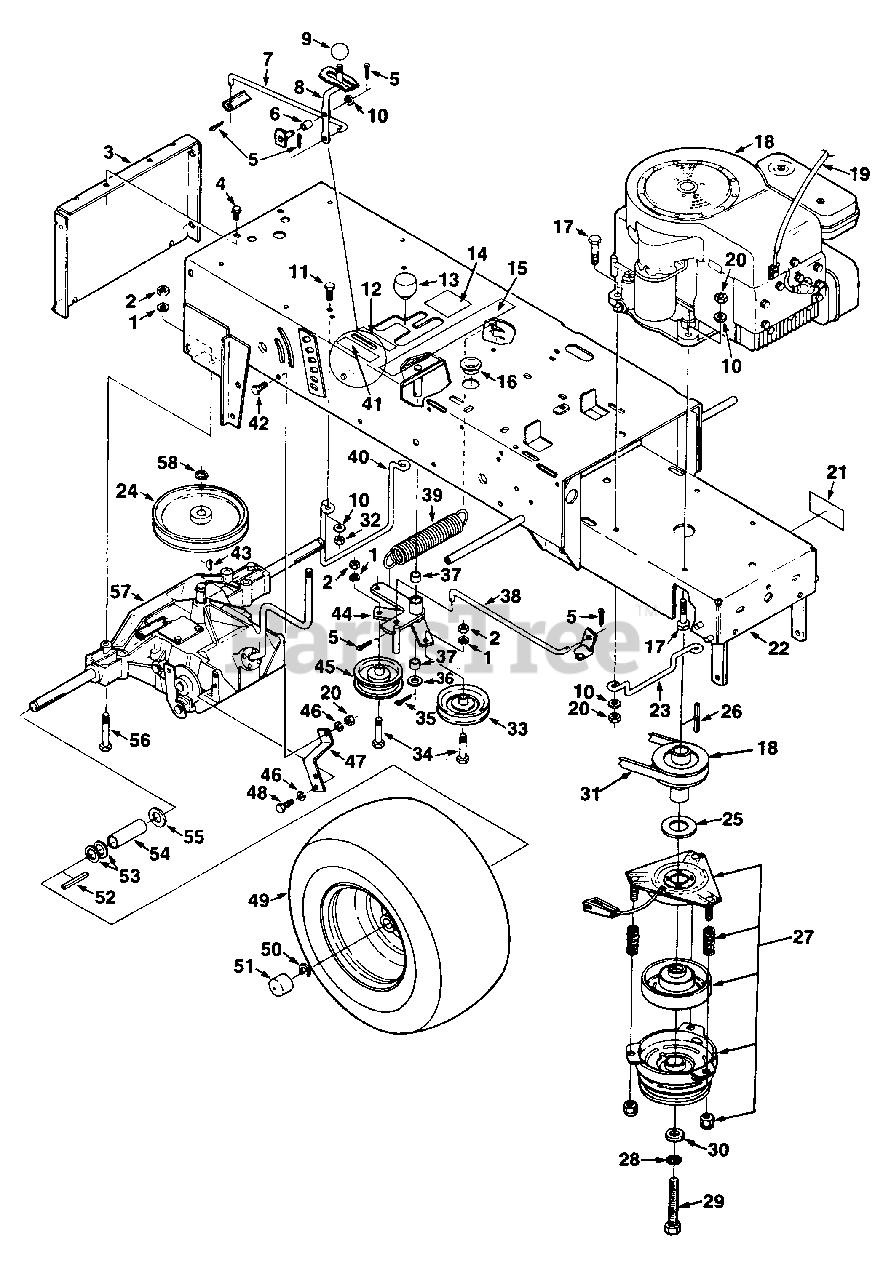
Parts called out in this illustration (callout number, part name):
1	WASHER- 3/8 lock
2	NUT- 3/8-16 hex
3	BRACKET- Hitch
4	BOLT- 1/4-20 x 9/16
5	PIN - Cotter 3/32 x 3/4
6	SPACER- Lever
7	ROD- Hi-lo sect.
8	LEVER- Hi-lo
10	WASHER- Flat 5/16
11	SCREW- 5/16-18 x 7/8 hex hd. cap
12	DECAL- Second & Reverse
13	KNOB- Shift lever
14	DECAL- First & Third
15	DECAL- Warning
16	BUSHING- Snap
17	SCREW- 5/16-18 x 1 3/4 hex hd. cap
18	PULLEY- Drive
19	CABLE- Retaining
20	NUT- 5/16-18
21	DECAL- Warning
22	FRAME ASSY.
23	GUIDE- Front belt
24	PULLEY- Drive
27	BRAKE- Electric clutch
28	WASHER- Lock 7/16 hvy.
29	SCREW- 7/16-20 x 2 3/4 hex hd. cap
30	CLUTCH- Retainer
31	BELT- Traction drive
32	NUT- 5/16-18 hex centerlock
33	IDLER- Inside
34	SCREW- 3/8-16 x 1 3/4 hex hd. cap
35	PIN- Cotter 3/16 x 1
36	WASHER- Flat 17/32
38	ROD- Idler actuator
39	SPRING- Extension
40	GUIDE- Rear belt
41	DECAL- Hi-Lo
42	SCREW- 5/16-18 x 5/8 hex hd. cap
43	KEY- 3/16 x 3/4
44	CLUTCH BEARING ASSY.
45	IDLER- Backside
46	WASHER- Lock 5/16 hvy.
48	SCREW- 5/16-18 x 3/4
49	REAR WHEEL ASSY.
50	RING- Retaining
51	HUB CAP- Rear wheel
52	KEY- 3/16 x 3/16 x 2 1/2
54	SPACER- Rear wheel
55	WASHER- Flat 13/16
56	SCREW- Hex 3/8-16 x 2 3/4
57	TRANSAXLE- 6 Speed
58	RING- Retaining
